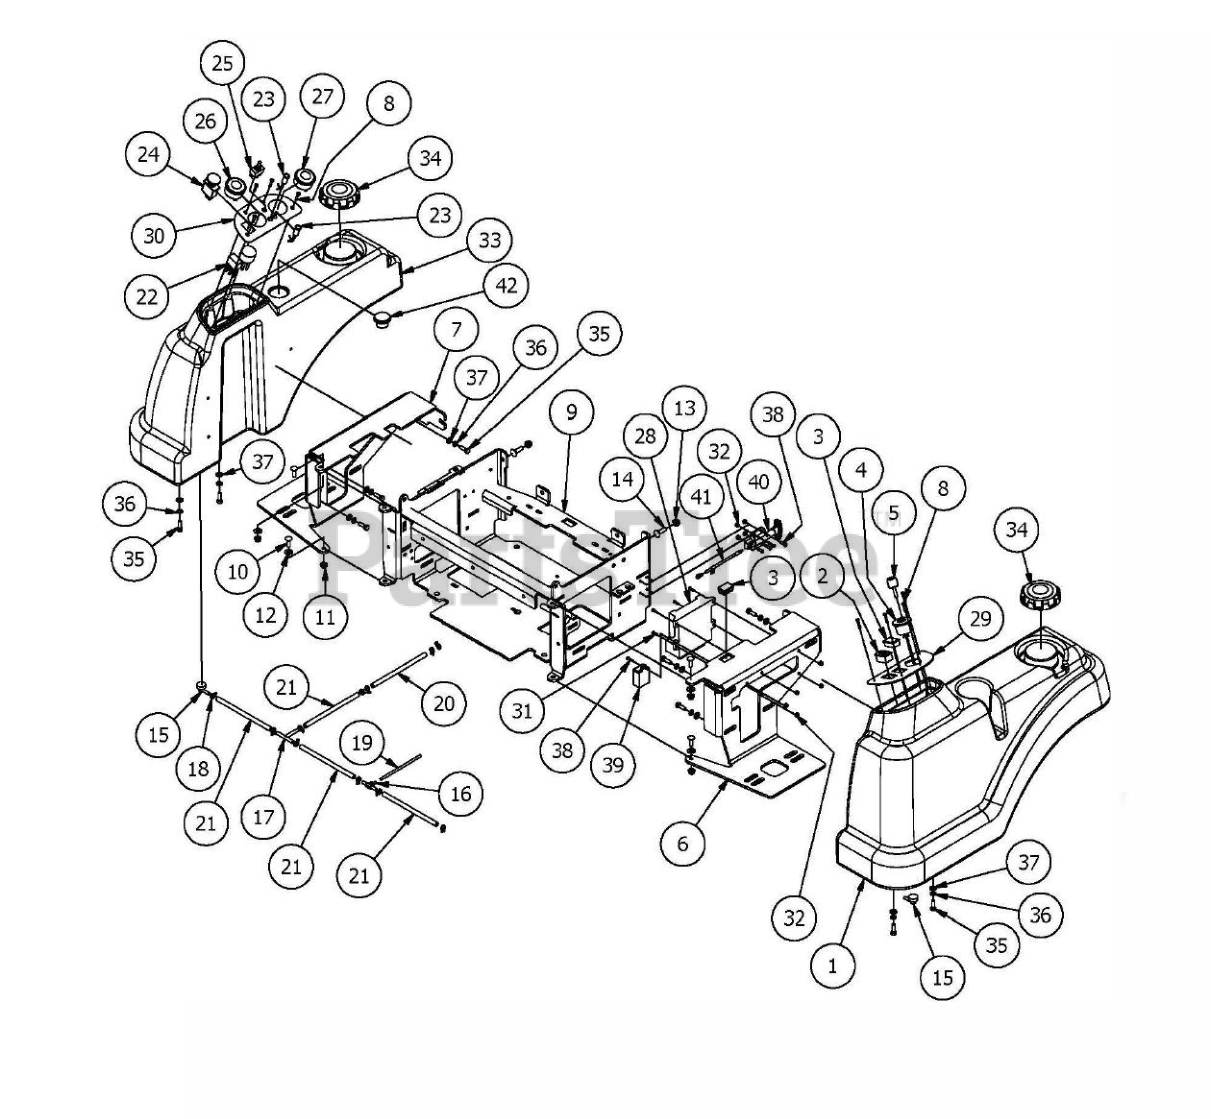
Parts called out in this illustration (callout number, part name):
1	Left Fuel Tank with Fender
2	Hour Meter
3	Light Plug
4	Ignition Switch
5	Ignition Key
6	Tank Supports-Left
7	Tank Support-Right
8	10-32 x 1 Button Head Bolt
9	Diesel Seat Frame
10	5/16" x 1" Carriage Bolt
11	5/16" Flange Nut
12	.360 ID Plastic Washer
13	3/8" Nylock Flange Nut
14	3/8" x 1 1/4" Carriage Bolt
15	Fuel Tank Hose Nipple w/ Filter
16	Brass fuel line T
17	fuel line T
18	1/4 Fuel Hose Clamp
19	3/16 Fuel Line
20	5/16" fuel line hose
21	1/4" Fuel Line Hose
22	Wiring Harness
24	PTO Engager
25	Deck Lift Joystick
26	2" Water Temperature Gauge
27	2" Oil Pressure Gauge
28	ECM for 1100cc Diesel
29	Control Panel (Left)
30	1100cc Diesel Control Panel
31	10-24 X 5/8 BS Button Head Bolt
32	10-24 Nylon Insert Locknut Zinc Orange Nylon
33	Right Fuel Tank with Fender
34	Diesel Fuel Cap - 3.5" Neck
35	5/16" x 1" Bolt
36	5/16" Lock Washer
37	5/16" Flat Washer
38	10-24 x 1 BS C/S 18-8 SS
39	Auto Shut Down for Cat Diesels
40	2016 T Handle Release
41	2015 Seat Latch Cable
42	Fuel Gauge and Grommet
